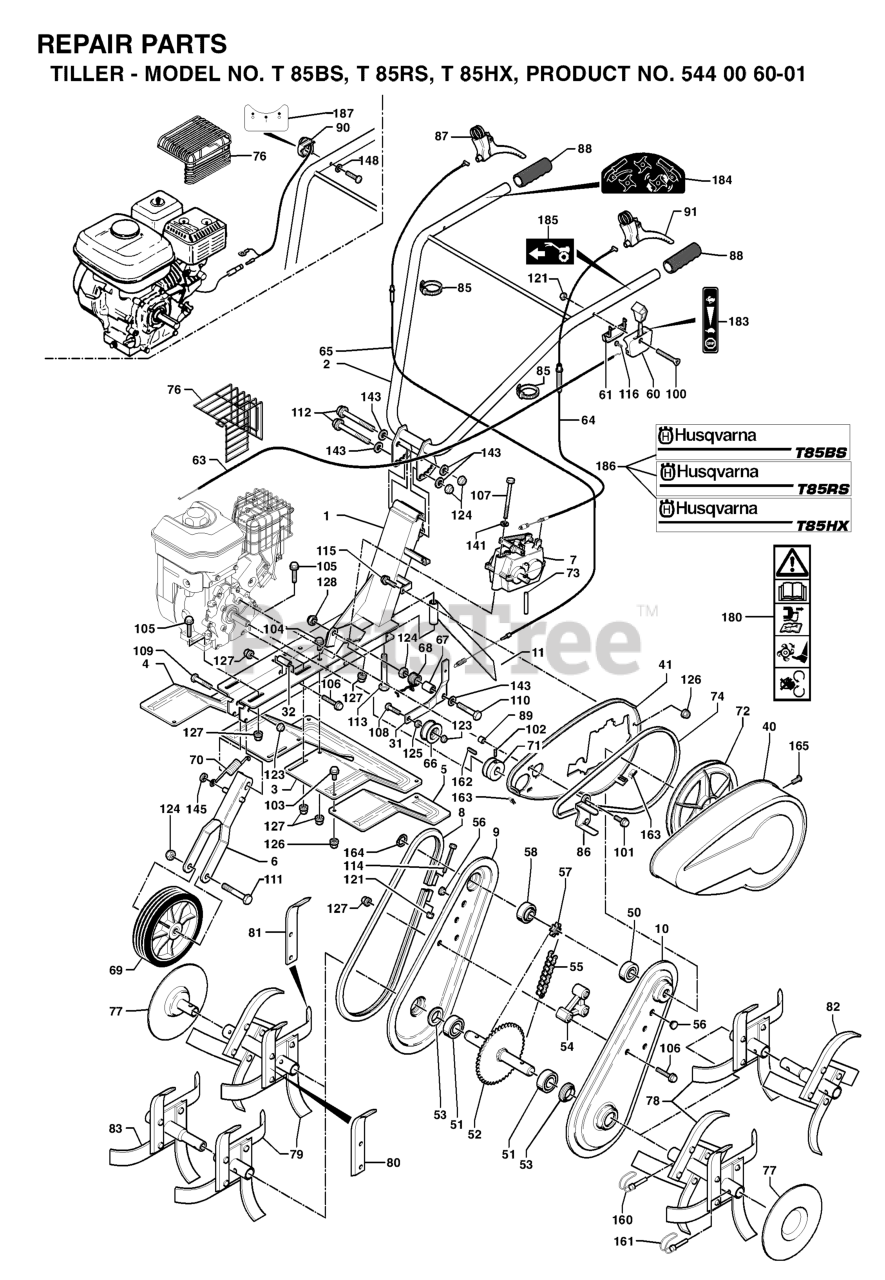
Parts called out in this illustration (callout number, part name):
31	ARM
55	DRIVE CHAIN
60	THROTTLE TRIGGER
61	THROTTLE CONTROL
64	CABLE GEAR PUBERT 0308010005
65	CABLE PUBERT 0308020043
69	WHEEL
91	GEAR SHIFT LEVER PUBERT 03070
121	Blocking nut M 6 Z
164	RETAINING RING
